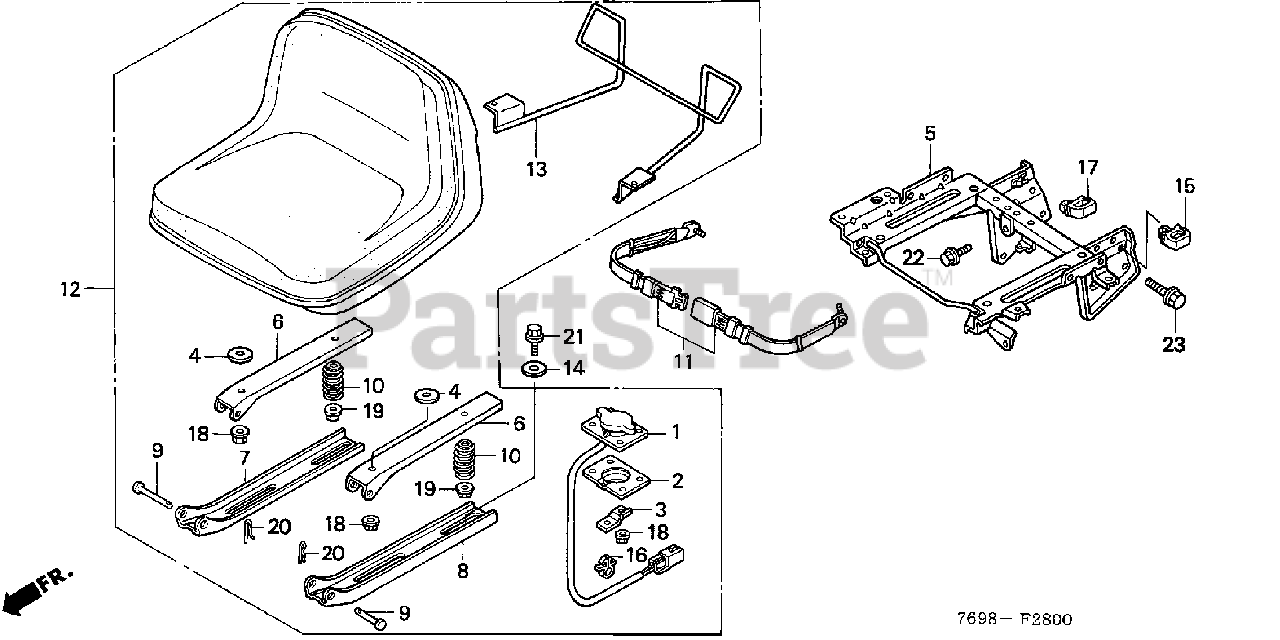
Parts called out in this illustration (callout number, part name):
1	SWITCH, SEAT
2	COVER, SEAT SWITCH
3	BASE, CLIP
4	WASHER (5MM)
5	FRAME, SEAT SUPPORT
6	BASE, SEAT (UPPER)
7	BASE, R. SEAT (LOWER)
8	BASE, L. SEAT (LOWER)
9	PIN, SEAT BASE (8MM)
10	SPRING, SEAT
11	SEAT BELT ASSY.
12	SEAT ASSY.
13	HOLDER, TOOL BOX
14	WASHER, ROTOR SETTING
15	CLIP, HARNESS (15MM) (BLUE)
16	CLIP, WIRE HARNESS (6MM) (WHITE)
17	CLIP, WIRE HARNESS
18	NUT, FLANGE (6MM)
19	NUT-WASHER (6MM)
20	PIN, LOCK (8MM)
21	BOLT, FLANGE (8X16)
22	BOLT, FLANGE (8X20)
23	BOLT, FLANGE (10X25)
